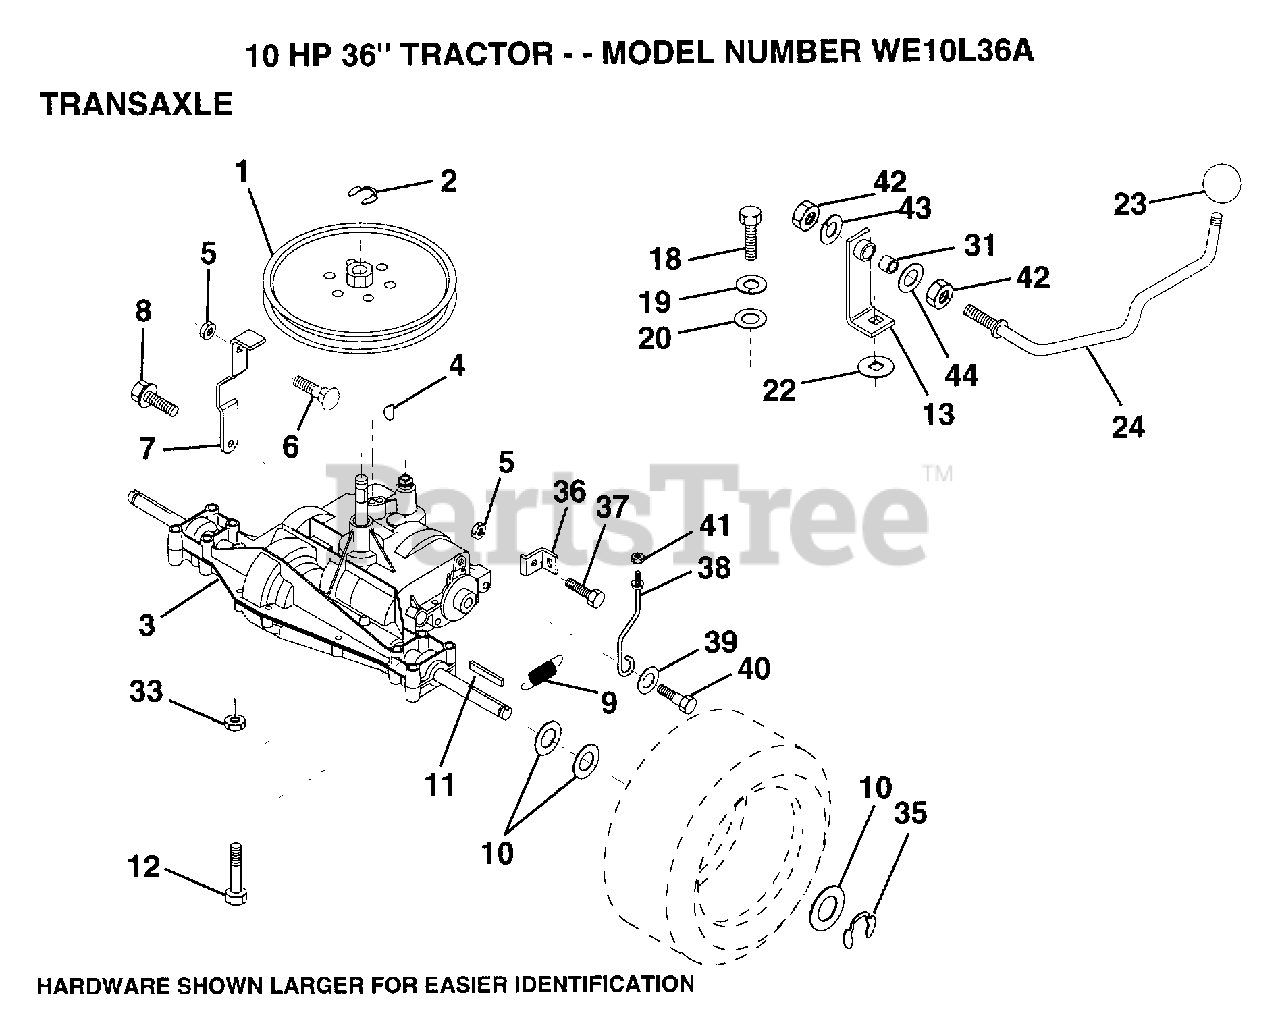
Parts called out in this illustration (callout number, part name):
1	PULLEY
3	TRANSAXLE DANA 5SP
6	BOLT
7	STRAP.TORQUE.LH
8	SCREW
10	WASHER
11	SQUARE KEY
12	BOLT
13	BRACKET.ASM.SHIFT
19	LOCKWASHER
20	WASHER LT
22	WASH-SHFT PLT LT
23	KNOB T (1/2-HOLE)
24	ROD.SHIFT.CNTR.LR
35	E-RING LT
36	BRACKET.BRAKE
37	BOLT
38	KEEPER.BELT.RH
40	BOLT SHD 5/16-18
41	NUT
42	NUT
43	LOCKWASHER
44	WASHER
